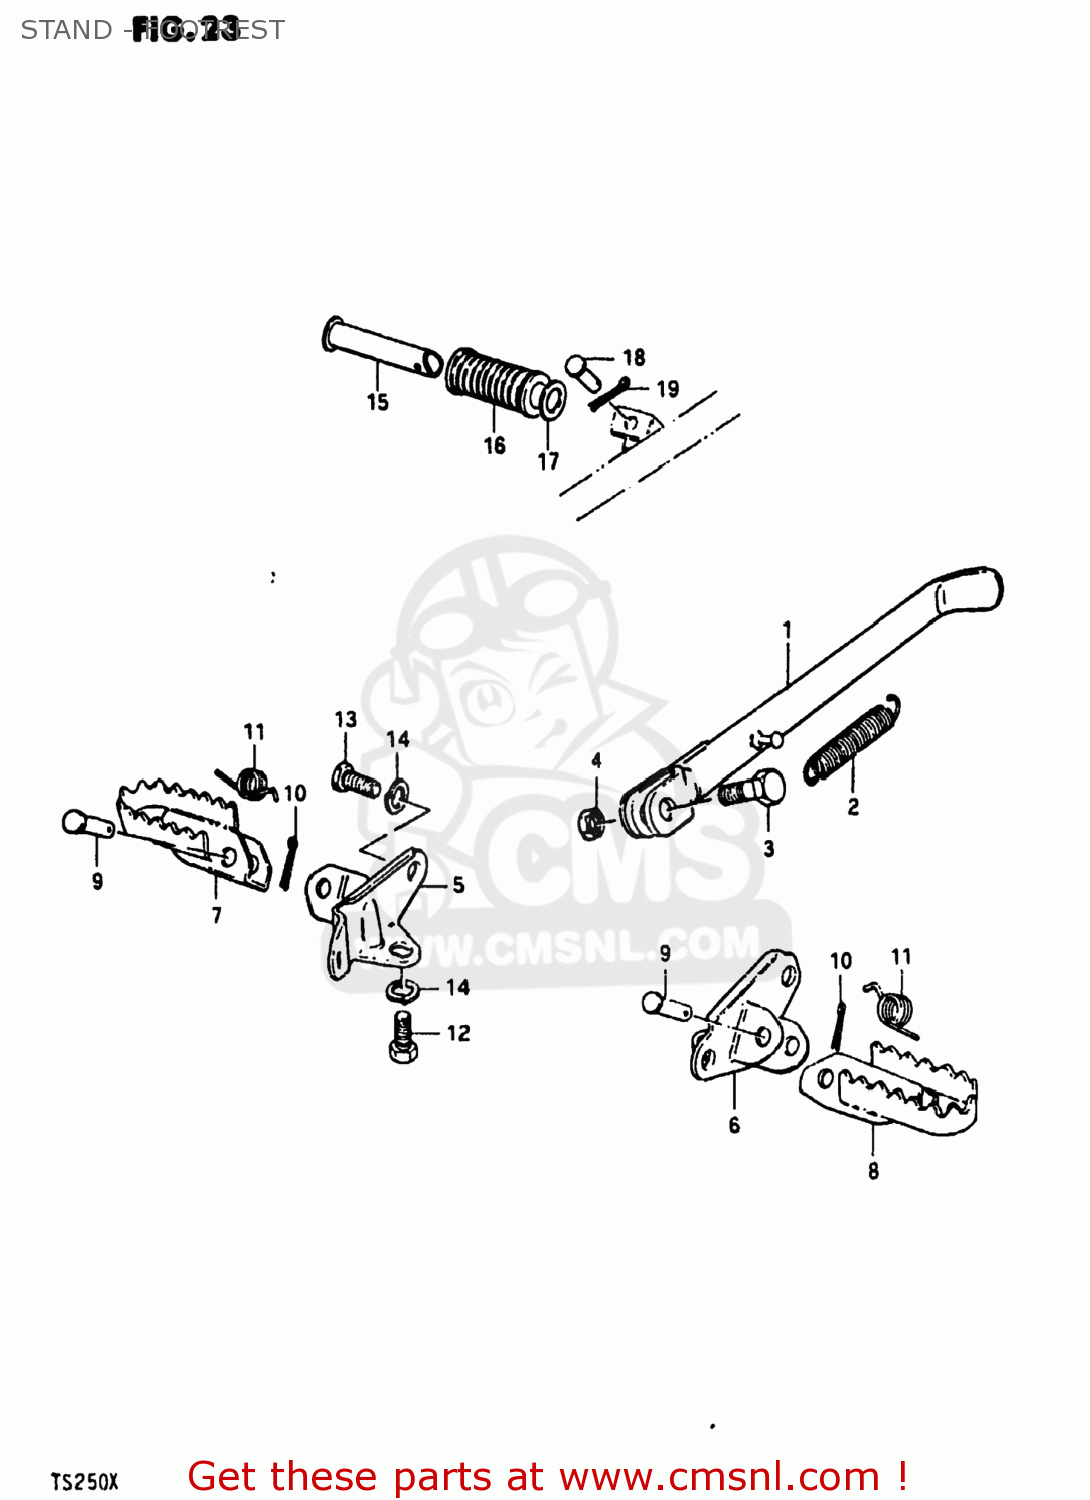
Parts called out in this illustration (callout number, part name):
1	STAND,PROP
2	SPRING
3	BOLT(10X30)
4	NUT
5	HOLDER,FRONT FOOTREST,RIGHT
6	HOLDER,FRONT FOOTREST
7	FOOTREST,FRONT
8	FOOTREST
9	PIN
10	PIN 20X20
11	SPRING
12	BOLT
13	BOLT 8X16
14	WASHER,LOCK,8.
15	BAR,FOOTREST RUBBER
16	RUBBER,PILLION FOOTREST
17	WASHER (19.5X32X2)
18	PIN
19	PIN 20X20
